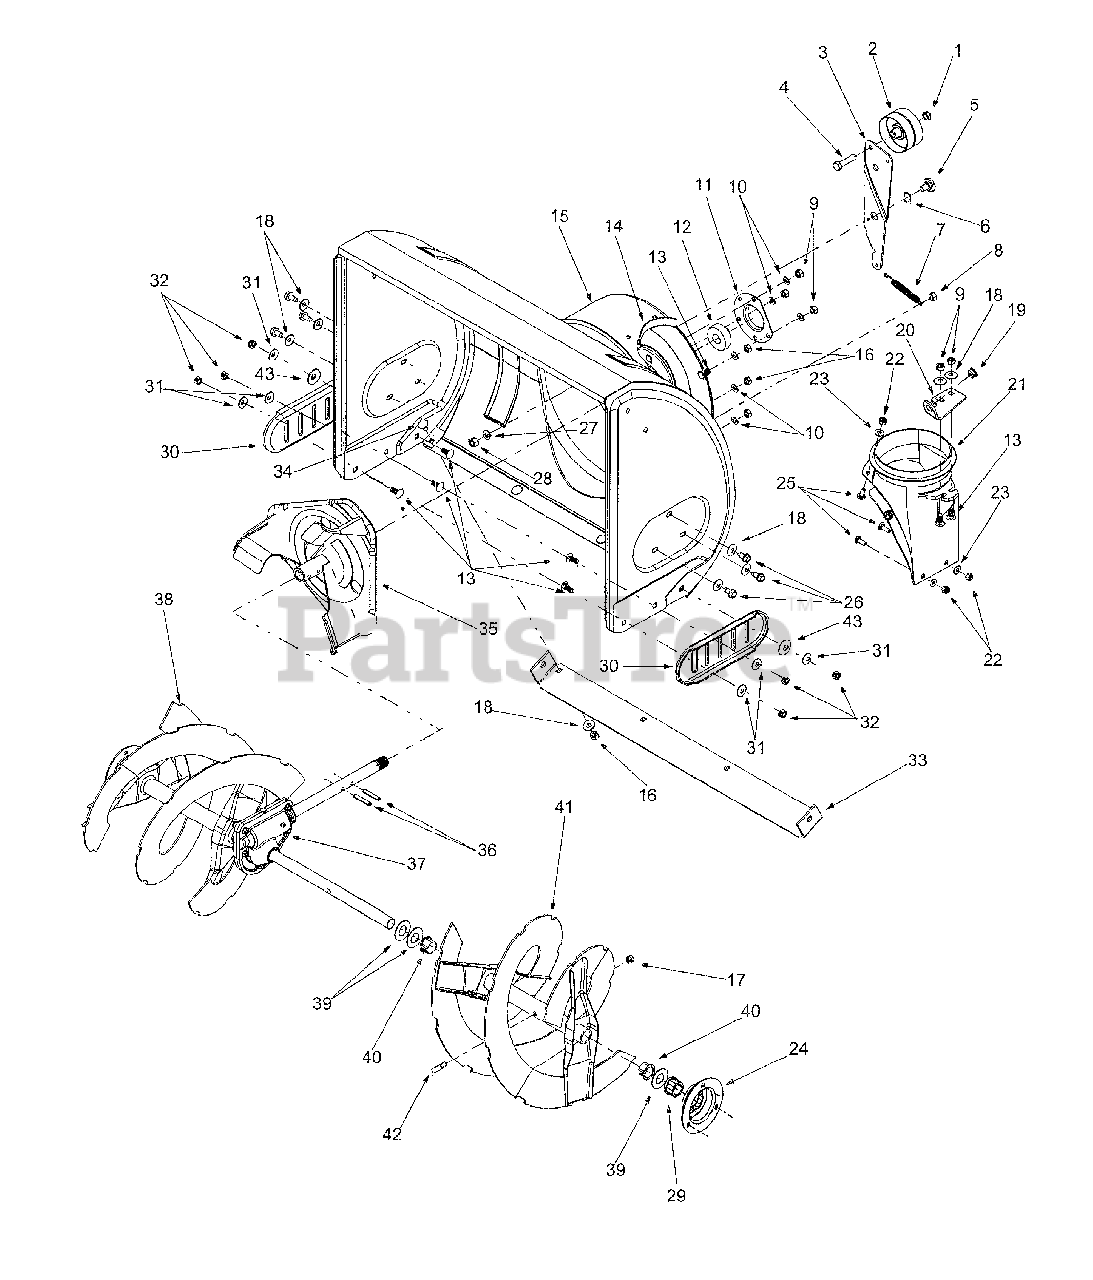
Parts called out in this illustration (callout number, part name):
1	Lock Jam Nut 3/8-24
2	Flat Idler
3	Auger Idler Arm
4	Hex Cap Screw 3/8-24 x 1.50
5	Shoulder Screw
6	Flat Washer .656 ID x 1.25 OD
7	Extension Spring
8	Hex Nut 5/16-18
9	Hex Nut 5/16-18
10	Lock Washer 5/16
11	Housing
12	Ball Bearing
13	Carriage Bolt 5/16-18 x .75
17	Lock Nut 5/16-18
18	Bell Washer
19	Bushing
20	Chute Crank Bracket
21	Chute Adapter
22	Hex Lock Nut 1/4-20
23	Flat Washer
24	Bearing Housing
25	Carriage Screw 1/4-20 x .75
26	Hex Washer Screw 5/16-18
27	Lock Washer 3/8
28	Hex Nut 3/8-16
29	Hex Flange Bearing
30	Skid Shoe
31	Bell Washer
32	Hex Nut 5/16-18
33	21.66" Shave Plate
33	23.66" Shave Plate
34	Carriage Bolt 5/16-18 x .62
35	Impeller Assembly
36	Pin
37	22" Gear Assembly
37	24" Gear Assembly
38	22" Spiral RH
40	Flange Bushing
41	22" Spiral LH
41	24" Spiral LH
42	Shear Bolt 5/16-18 x 1.5
43	Flat Washer, .344 x 1.12 x .87
